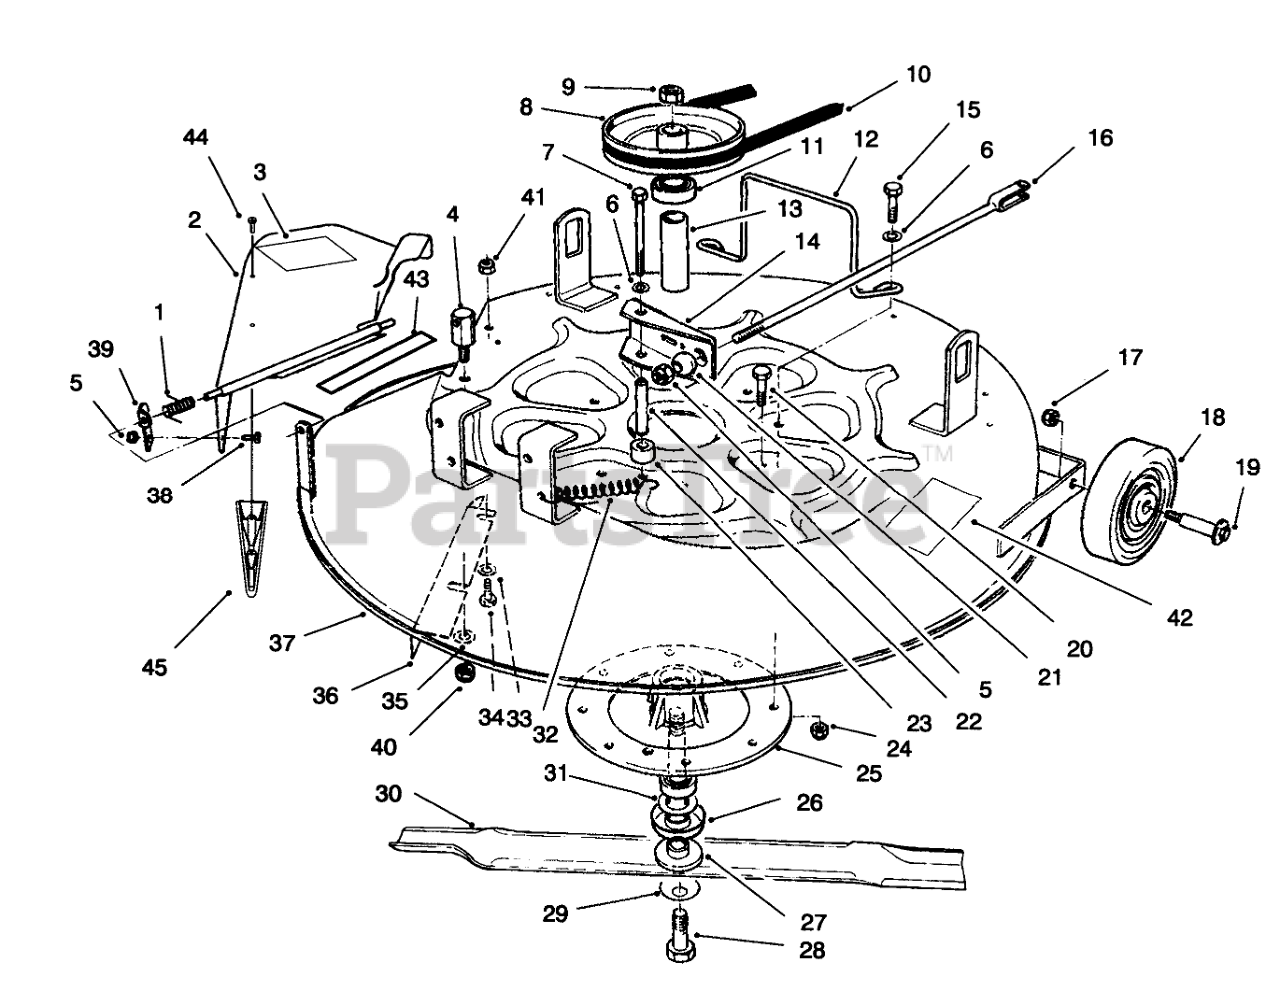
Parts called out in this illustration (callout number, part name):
1	SPRING
2	Deflector (Incl. Ref. #3)
3	DECAL-DANGER
4	POST-PIVOT
5	NUT-HEX
6	WASHER-PLAIN
7	SCREW-HH
8	PULLEY-DECK
9	NUT-HEX
10	V-Belt
11	BEARING-BALL
12	GUIDE-DECK BELT
13	SPACER-BEARING
14	DECK BRAKE ASSEMBLY
15	SCREW-HH
16	DECK BRAKE ROD WA
17	NUT-LOCK, NI
18	WHEEL-DECK
19	BOLT-WHEEL
20	SCREW-HH
21	BALL-SWIVEL, STOP
22	POST-BRAKE MTG
23	SPACER-DECK BRAKE
24	NUT-LOCK, NI
25	CASTING-SPINDLE
26	SHIELD-BEARING
27	SHAFT-SPINDLE
28	SCREW-HH
29	WASHER-BELLEVILLE
30	Blade
31	SPACER
32	SPRING-EXTENSION
33	WASHER-FLAT
34	SCREW-HHF
35	WASHER-FLAT
36	BAFFLE PLATE RED
37	Deck (Incl. Ref. #42)
38	SCREW-HH
39	BRACKET-DEFLECTOR
40	NUT-LOCK, NI
41	NUT-LOCK, NI
42	DECAL-DANGER
43	DECAL-DANGER
44	SCREW-PPH
45	KICKER
